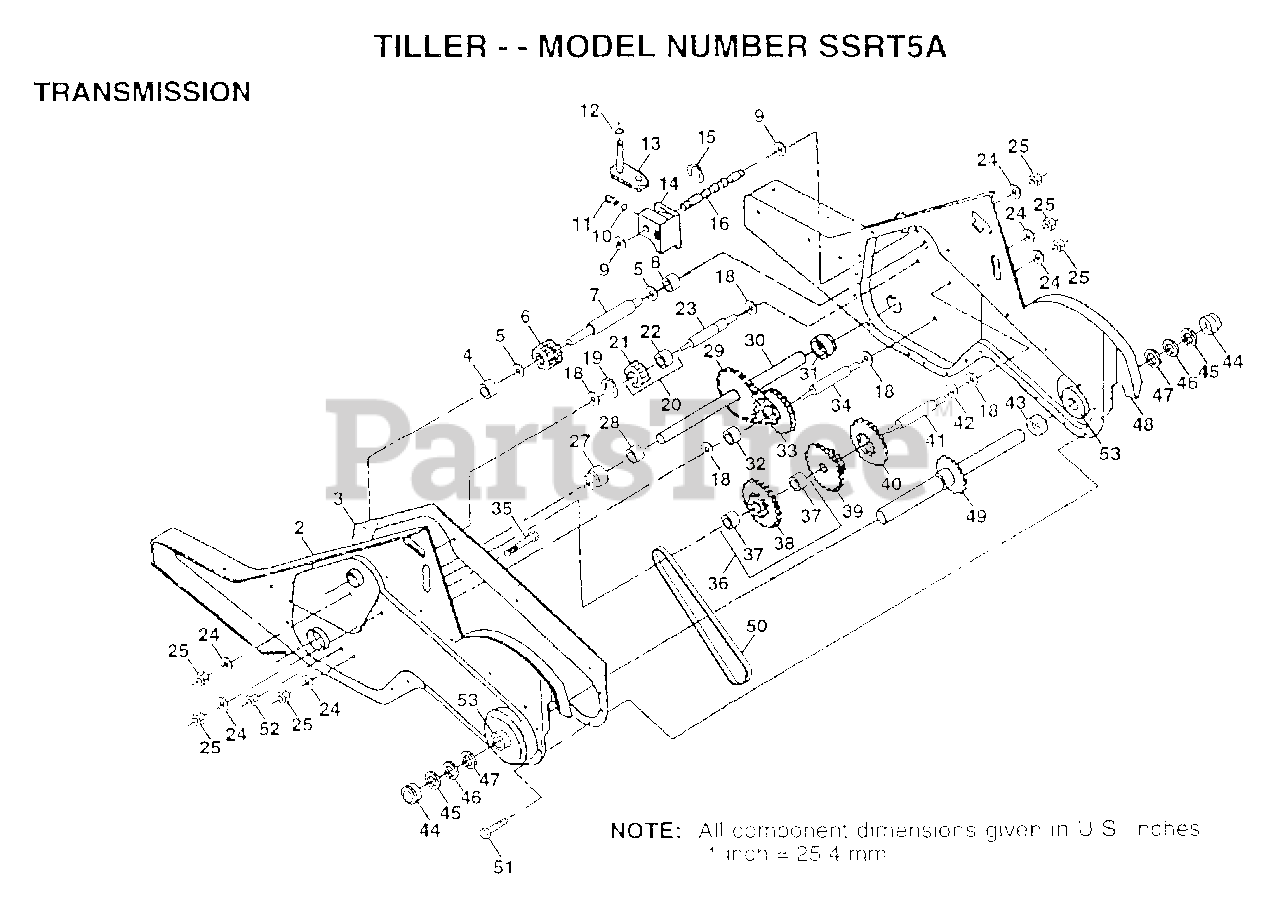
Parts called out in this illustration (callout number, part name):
2	GEARCASE LH W/BRG
3	GASKET TI
4	NEEDLE BRNG LT
5	"T, BEARING"
6	GEAR PINION INPUT
7	"SHAFT.INPUT.""D"""
8	"TI, BEARING"
9	WASHER SEAL CRT
11	SPRING-SHIFT CRT
12	O-RING TI
13	BRACKET ASM SHIFT
14	SHIFT FORK TI
15	KLIP RING
16	SHAFT.SHIFT.4.250
18	WASHER
19	KLIP RING
20	GEAR ASSY CRT
21	GEAR-REV IDLR CRT
22	NEEDLE BEARING TI
23	SHAFT CRT
24	LOCKWASHER
25	NUT.ASF.HEX.7/16
27	BEARING.SHAFT.LH.
28	BUSHING TI
29	CHAIN CRT
30	GROUND SHAFT ASSY
31	BEARING.SHAFT.RH.
32	SPACER TI
33	SPRCKT 8 GEAR CRT
34	SHFT 2ND RED. CRT
35	SCRW WHIZ LOK CRT
36	SPROCKET ASM.
37	BEARING
39	GEAR TI
40	GEAR TI
41	REDUCTION SHFT TI
42	BRNG RACE
43	SPACER TI
44	CUP.FORMED.
45	RING SPIRAL CRT
46	SEAL RING RUBBER
47	OIL SEAL STD
48	GEARCASE RH W/BRG
49	TINE SHAFT
50	CHAIN.50 LINK TI
51	SCREW
52	NUT.HEX.5/16-18
